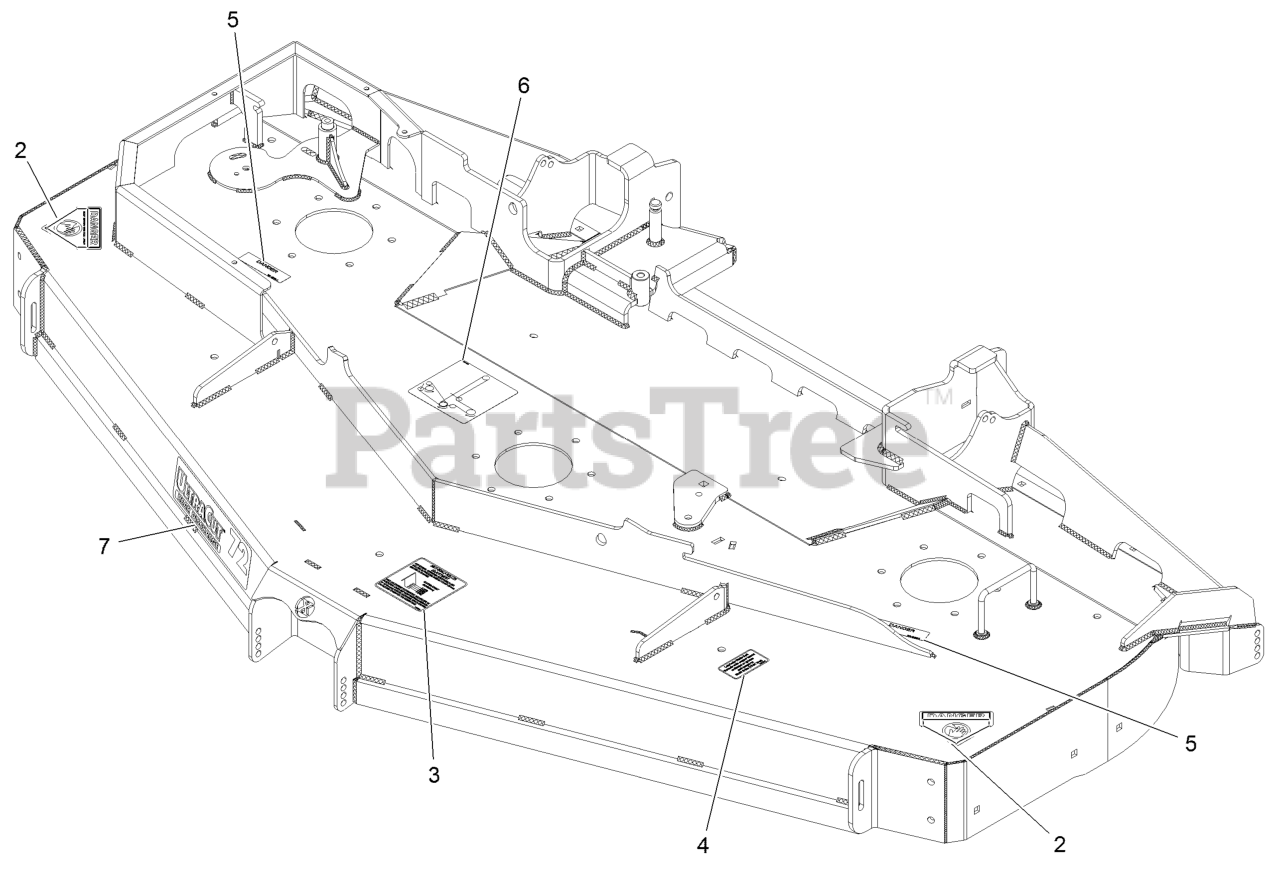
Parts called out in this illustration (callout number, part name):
2	DECAL-DANGER
3	DECAL,ANTISCALP
4	DECAL,BOLT TORQUE
5	DECAL-COVER, MISSING
6	DECAL-ROUTING, BELT
7	DECAL,REAR DISCHARGE 72
